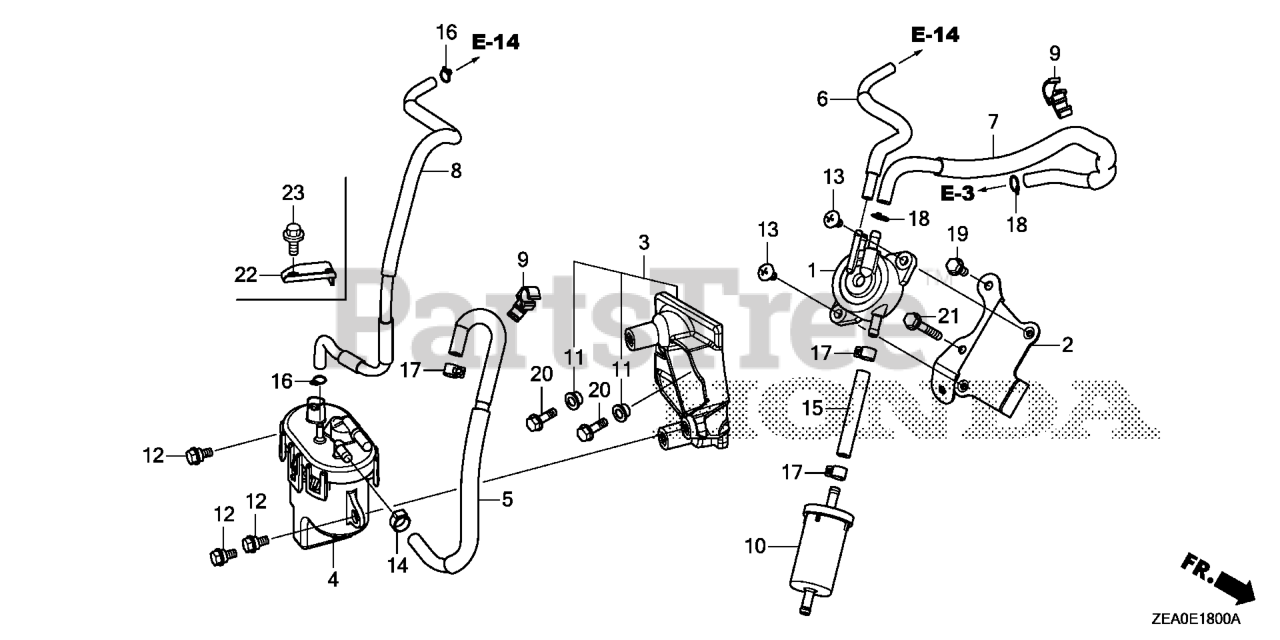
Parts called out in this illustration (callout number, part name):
1	PUMP ASSY., FUEL (MSDS)
2	STAY, FUEL PUMP
3	STAY, HIGH PRESSURE PUMP
4	PUMP ASSY., FUEL (HIGH PRESSURE)
5	TUBE, B FUEL
6	TUBE, PURGE
7	TUBE, DIAPHRAGM
8	TUBE, VAPOR
9	CLAMP A, FUEL TUBE
10	FILTER, FUEL
11	COLLAR, FAN COVER
12	BOLT, SPECIAL (6X13)
13	SCREW, TRUSS (6X12)
14	CLAMP, HOSE CALKING (D12.3)
15	TUBE, FUEL (5.3X70)
16	CLIP, TUBE (B8)
17	CLAMP, TUBE (D10)
18	CLIP, TUBE (C11)
19	BOLT, FLANGE (6X14)
20	BOLT, FLANGE (6X20)
21	BOLT, FLANGE (6X45)
